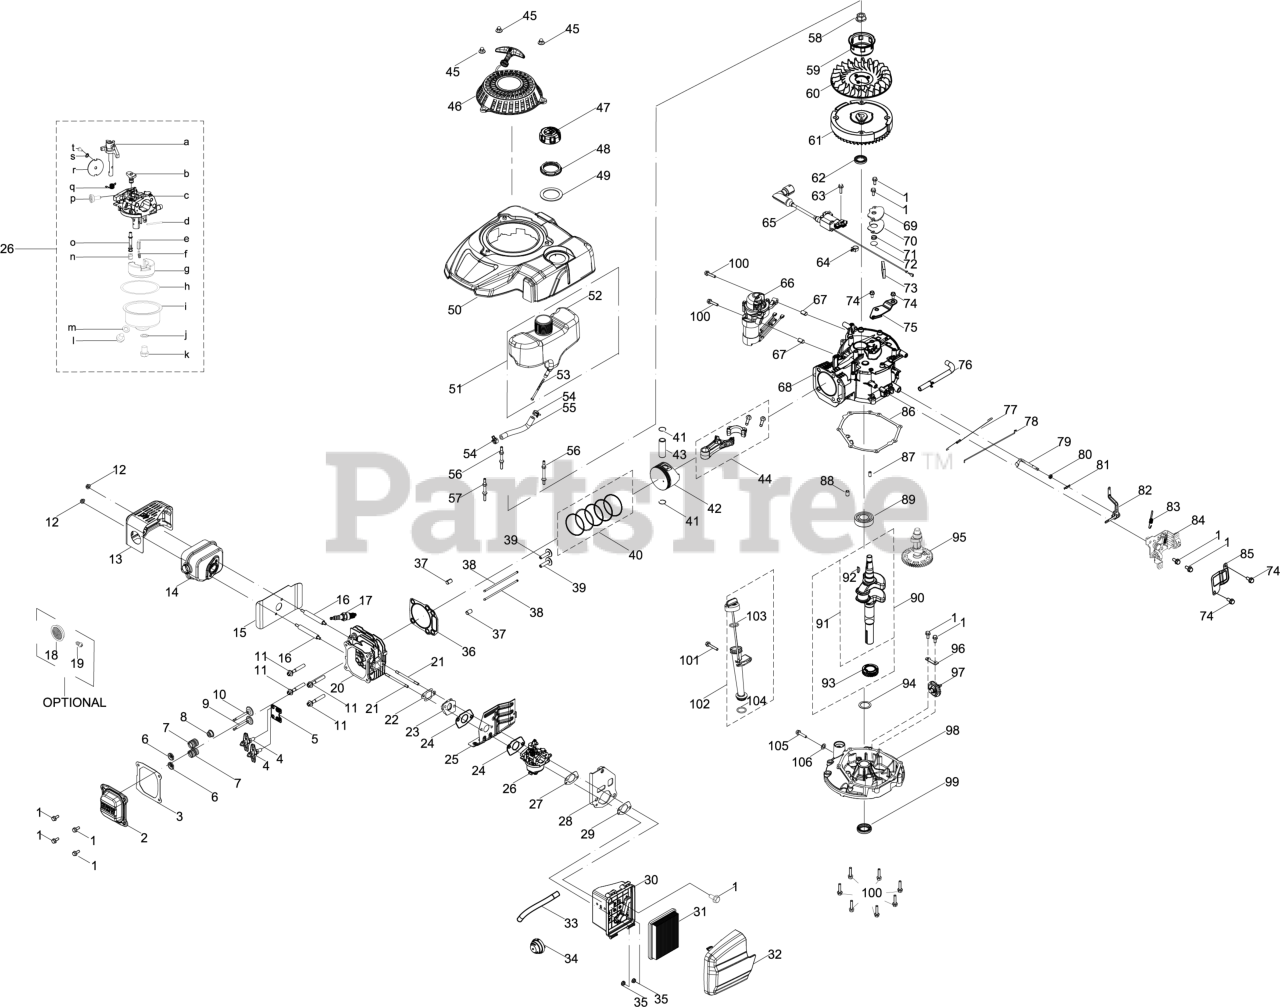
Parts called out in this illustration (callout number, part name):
1	BOLT M6-1 x 14 GR8.8
2	VALVE COVER
3	VALVE COVER GASKET
4	ROCKER ARM ASSEMBLY
5	PUSH ROD GUIDE
6	INTAKE VALVE SPRING RETAINER
7	VALVE SPRING
8	INTAKE VALVE SEAL
9	EXHAUST VALVE
10	INTAKE VALVE
11	SCREW M8 x 54 GR10
13	MUFFLER SHIELD
15	MUFFLER GASKET
16	STUD M6-1 x 95
17	SPARK PLUG
18	SPARK ARRESTOR
19	SCREW M3.5 x 9.5
20	CYLINDER HEAD
21	CARBURETOR STUD-M6 x 87
22	CARBURETOR GASKET
23	CARBURETOR INSULATOR
24	CARBURETOR GASKET
25	HEAT SHIELD
26	CARBURETOR
27	AIR FILTER BRACKET GASKET
28	AIR FILTER BRACKET
29	AIR FILTER BASE GASKET
30	AIR FILTER BASE
31	AIR FILTER
31	Cub Cadet AIR FILTER
31	Genuine Factory Parts AIR FILTER
32	AIR FILTER COVER
33	PRIMER HOSE
34	VENTED PRIMER ASSEMBLY
36	CYLINDER HEAD GASKET
40	PISTON RING 4PC SET
41	PISTON PIN SNAP RING
44	CONNECTING ROD ASSEMBLY
45	ACORN NUT
46	RECOIL STARTER ASSEMBLY
47	FUEL CAP ASSEMBLY
48	FUEL TANK NUT
49	FUEL TANK UPPER GROMMET
50	ENGINE SHROUD ASSEMBLY
51	Fuel Tank Assembly
53	FUEL FILTER
54	HOSE CLAMP
55	FUEL HOSE
56	STARTER/SHROUD REAR STUD
57	STARTER/SHROUD FRONT STUD
58	FLYWHEEL NUT
59	COOLING FAN
60	STARTER CUP
62	CRANKSHAFT SEAL
63	BOLT M6-1 x 20 GR8.8
64	WIRE SUPPORT CLAMP
65	IGNITION COIL ASSEMBLY
66	ELECTRIC STARTER ASSEMBLY
67	DOWEL PIN
69	BREATHER COVER PLATE
70	BREATHER GASKET
71	BREATHER VALVE SPRING
72	BREATHER VALVE
73	BREATHER SCREEN
74	BOLT M6-1 x 12 GR8.8
75	AIR VANE COVER
76	BREATHER HOSE ASSEMBLY
77	THROTTLE LINKAGE SPRING
78	THROTTLE LINKAGE
79	GOVERNOR ARM SHAFT
82	GOVERNOR ARM ASSEMBLY
83	Governor Spring
84	VARIABLE SPEED CONTROL ASSEMBLY
85	VARIABLE SPEED CONTROL COVER
86	CRANKCASE COVER GASKET
87	DOWEL PIN 7 X 14
88	DOWEL PIN 9 X 14
90	CRANKSHAFT
91	CRANKSHAFT
92	WOODRUFF KEY
93	DRIVE TIMING GEAR
94	THRUST WASHER
96	GOVERNOR GEAR MOUNTING PLATE
97	GOVERNOR GEAR/SHAFT ASSEMBLY
98	CRANKCASE COVER
99	LOWER CRANKSHAFT OIL SEAL
100	BOLT-M6-1 x 28 GR8.8
101	BOLT M6-1 x 35 GR8.8
102	OIL DIPSTICK ASSEMBLY
103	O-RING
105	OIL DRAIN PLUG
106	FLAT WASHER
P	SPEED IDLE SCREW
